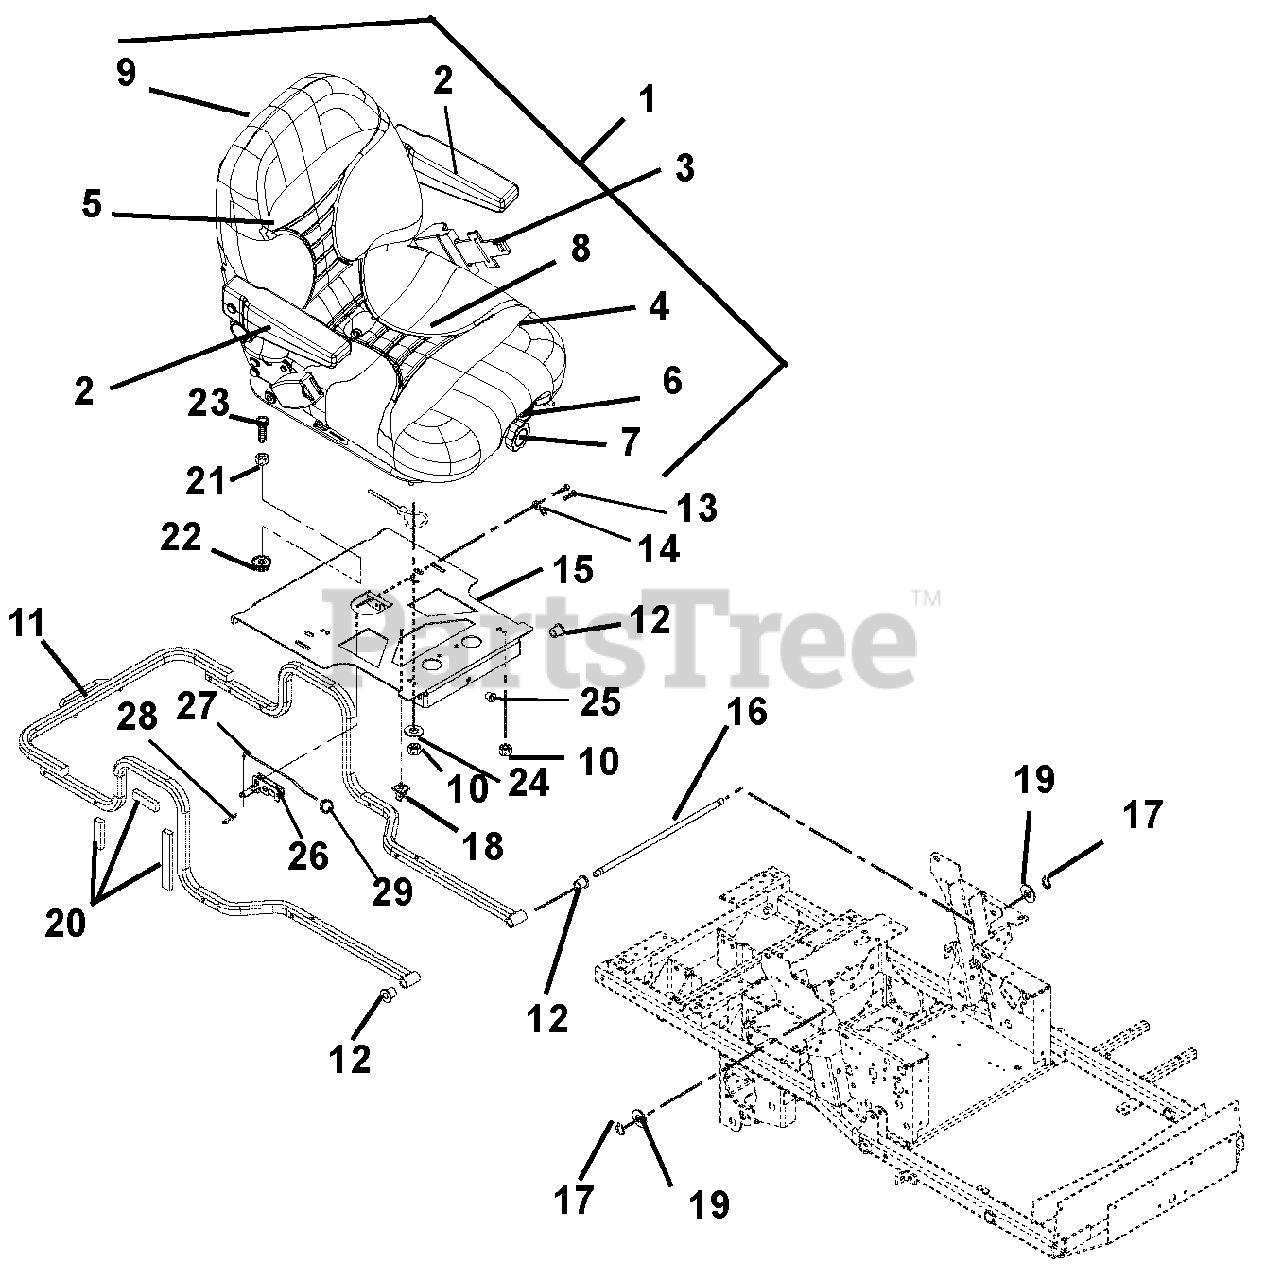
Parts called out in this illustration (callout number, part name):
1	SEAT, GREY W/ SEAT BELT
2	KIT, PLUSH 5300 ARMREST - PAIR
3	KIT, RETRACTABLE SAFETY BELT
4	KIT-SEAT CUSHION-LIGHT GRAY
5	KIT-BACK CUSHION-LIGHT GRAY
6	KIT-SEAT SLIDE
7	KIT-SEAT KNOB
8	KIT-SPRING AND SADDLE
9	KIT-SEAT BACK PANEL
10	@NUT-LK-TOP-FLG .31-18 YWZC
11	WMT-HOOD FRAME - L/C
12	BSHG-FLG .515X.750X.745X1.00NY
13	@BLT-HEX .25-20X1.00 GR5 YWZC
14	@WSHR-LK .25X.062 REG YWZC
15	PLATE, SEAT 200 XDZ WITH LATCH
16	ROD - SEAT FRAME PIVOT
17	RG-RTNG-EXT .500X.050 (SNAP)
18	ROUTING CLIP (1/2" ID)
19	@WSHR-FL-STL.531X1.06X.095YWZC
20	VHB TAPE 4941F
21	@NUT-HEX .50-13 YWZC
22	@NUT-LK-TOP-FLG .50-13 YWZC
23	@BLT-HEX .50-13X1.50 GR5 YWZC
24	WSHR-FL-STL .344X1.125X.135
25	BUSHING, POLYLINER-.38 SNAPIN
26	LATCH-ROTARY-PUSH TO CLOSE
27	ROD-SEAT LATCH RELEASE
28	@PIN-CTR .12X.75 EXTPRSQCT YWZ
